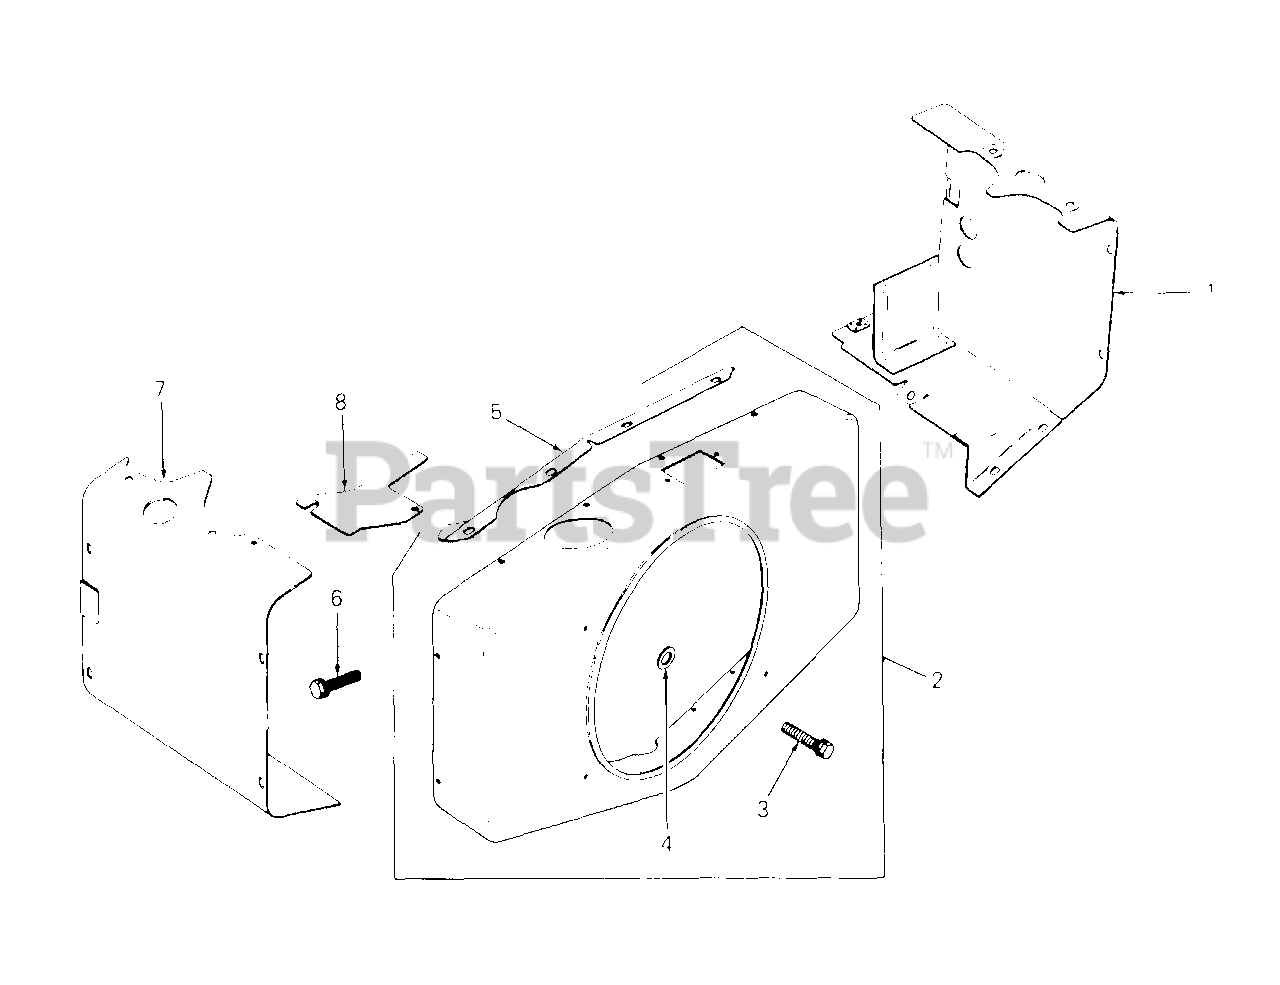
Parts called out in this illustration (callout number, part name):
1	Baffle, #1 Cylinder Head
2	Kit, Blower Housing
3	Screw, Self Tap, 1/4-20 X 5/8
4	Washer, Flat, 1/4
5	Support, Upper Housing
6	Screw, Hex Wash Hd, 1/4-20 X 7/16
7	Baffle, #2 Cylinder Head
8	Baffle, #2 Cylinder Top
